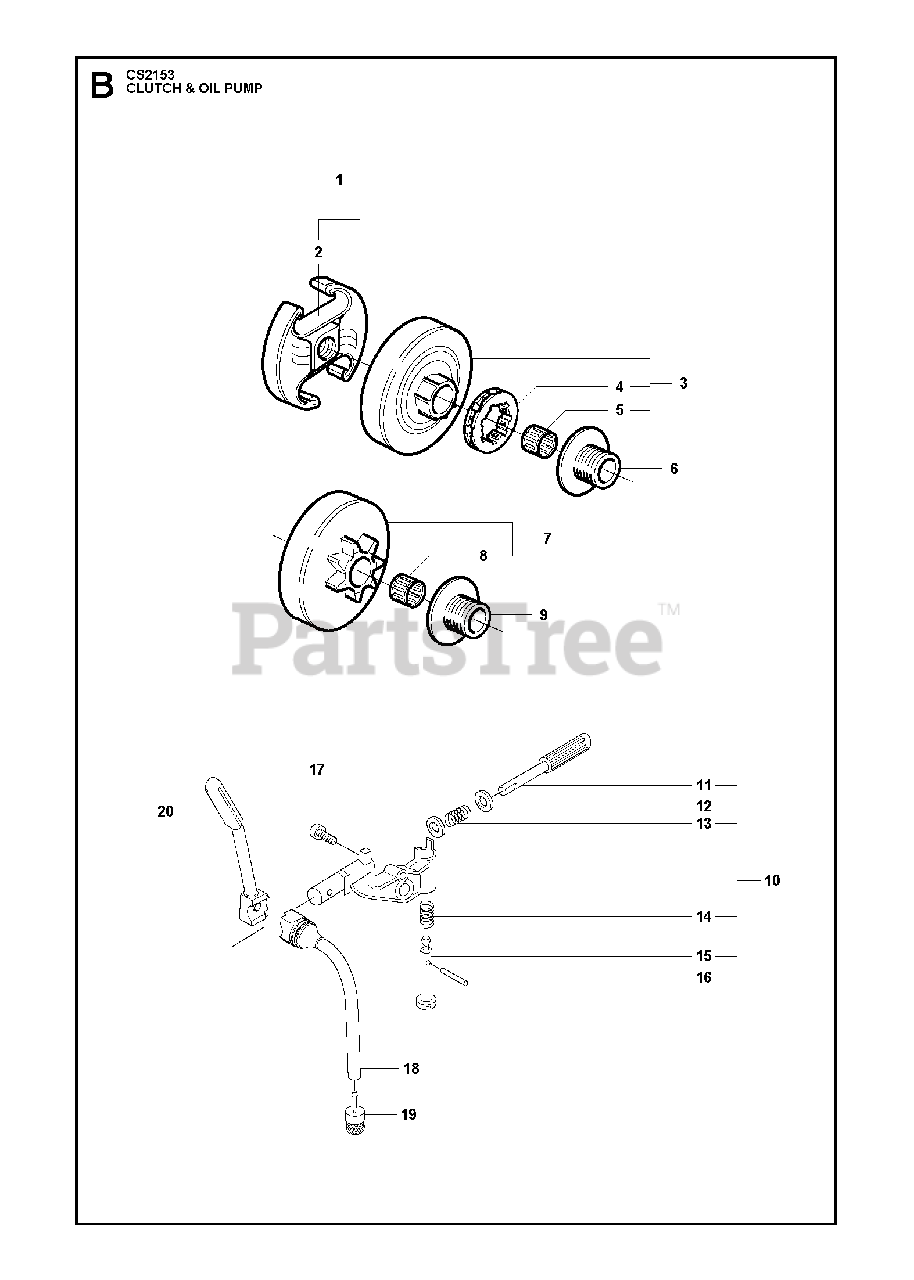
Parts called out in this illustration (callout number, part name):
1	CLUTCH
2	SPRING
3	CLUTCH DRUM
4	RIM SPROCKET 7T .325
5	NEEDLE BEARING
6	PUMP PINION
7	RP CLUTCH DRUM
8	NEEDLE BEARING
9	PINION
10	OIL PUMP ASSY
11	PUMP PISTON
12	WASHER
13	SPRING
14	SPRING
15	SCREW
16	PIN
18	HOSE
19	OIL PLUMMET
20	OIL PRESSURE HOSE
